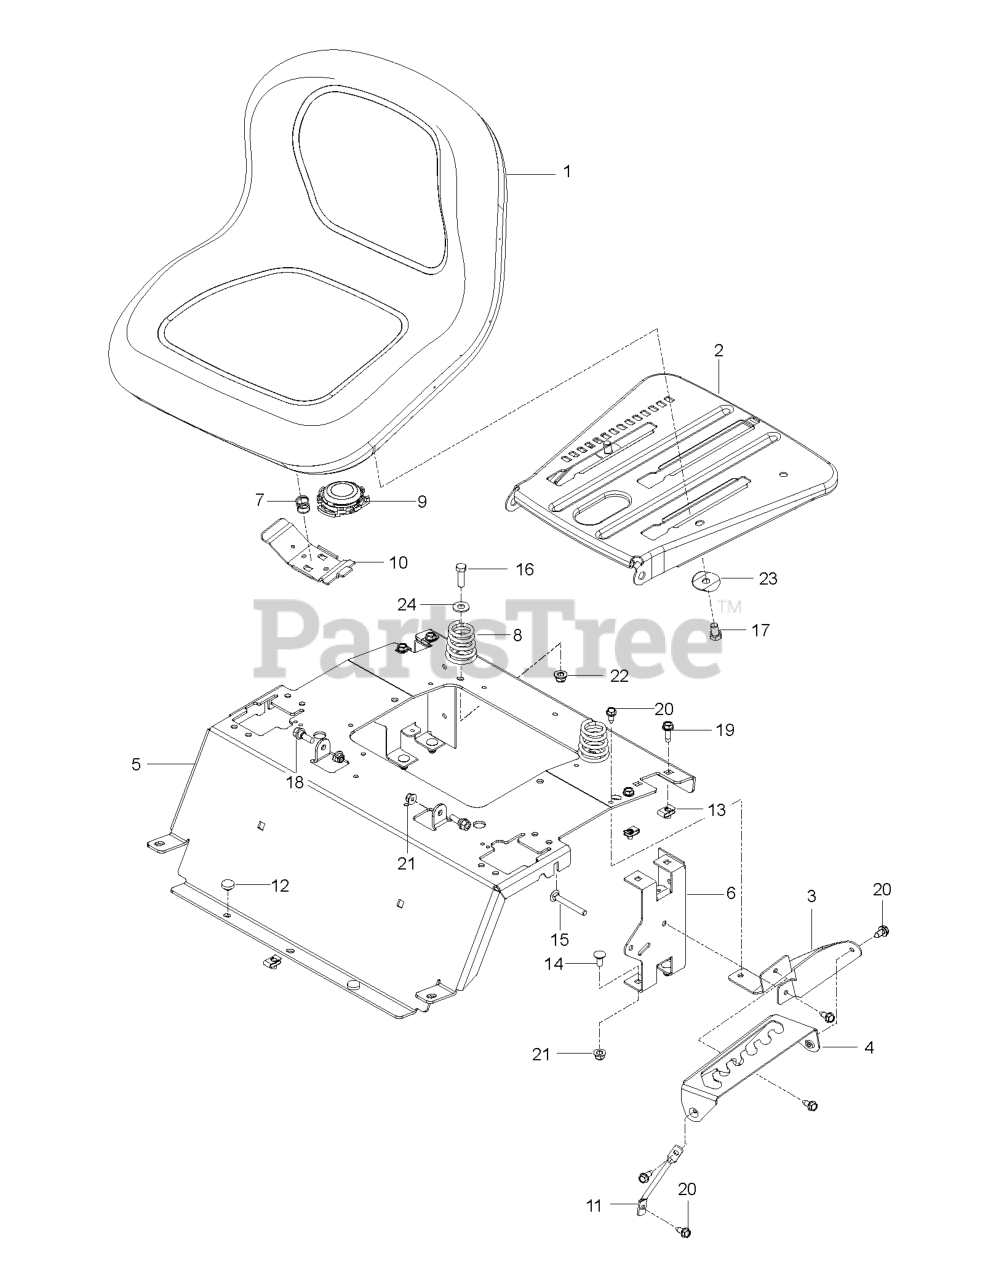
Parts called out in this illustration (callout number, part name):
1	SEAT.TH150.MS498.GRY.HUSQ.TEX
2	Seat Slide Plate, Pnt
3	PLATE.SUPPORT.DECK.LIFT.X431
4	PLATE.DECK.LIFT.X431
5	PLATE.SUPPORT.SEAT.RZ.ORANGE
6	SUPPORT REAR SEAT BLACK
7	SPRING.LATCH.SEAT.TEX
8	SPRING.COMPRESS.SEAT.
9	SWITCH.SEAT.DELTA.OPC.
10	HANDLE.SLIDE.SEAT.TEX.BLACK
11	SUPPORT.LEG.DECK.LIFT
12	GROMMET.BUMPER
13	U-CLIP 5/16-18 NUT RETAINER
14	BOLT 5/16-18 X3/4 ZN/YEL GR 5
15	RHSNB 5/16-18 X 2-1/2 GR5 ZD
16	BOLT
17	HCS 3/8-16 X 5/8 GR 5 ZD
18	BOLT, SHOULDER
19	SCREW
20	BOLT.5/16HEX.WHS.HD
21	5/16-18 NYLOC FLANGE NUT
22	NUT 3/8-16 HEX FLG NYLOC ZD
23	Winged Washer, 38Id 1
24	WASHER 3/8 FLAT
